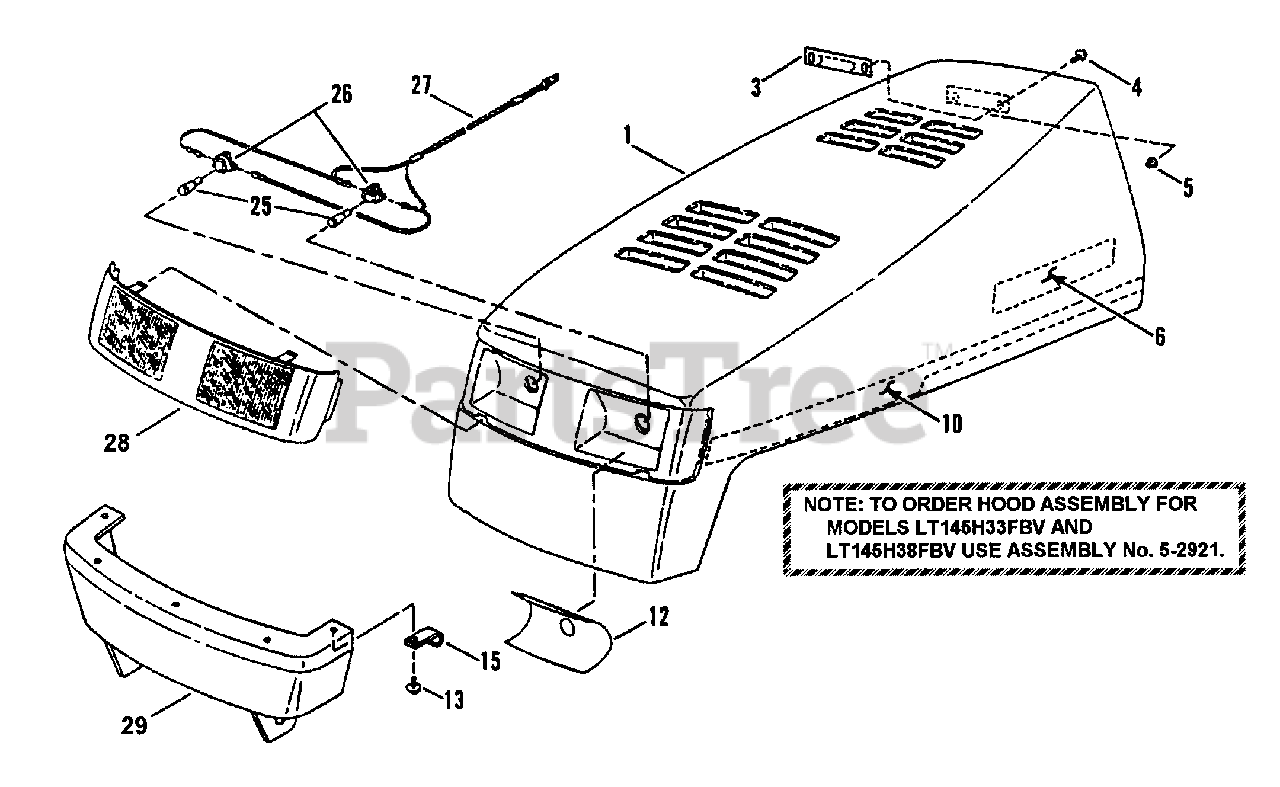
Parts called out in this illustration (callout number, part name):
1	HOOD
3	LATCH, Spring
4	SCREW, 1/4-20 x 5/8" Truss Head, Torx
5	NUT, 1/4-20 Hex Nyloc
6	DECAL - SNAPPER, 8" Molded Logo, Silver Letters
10	DECAL, Hood (Right Hand)
12	DECAL, Clear Lens (Left Hand)
13	SCREW, M4.8 x 1.59 x 16.00MM, Special
15	CLIP, "J"
25	BULB, Headlights
26	SOCKET, Headlight Bulb
27	HARNESS, Headlight Wiring
28	LENS, Clear
29	BUMPER, Front Hood Support
